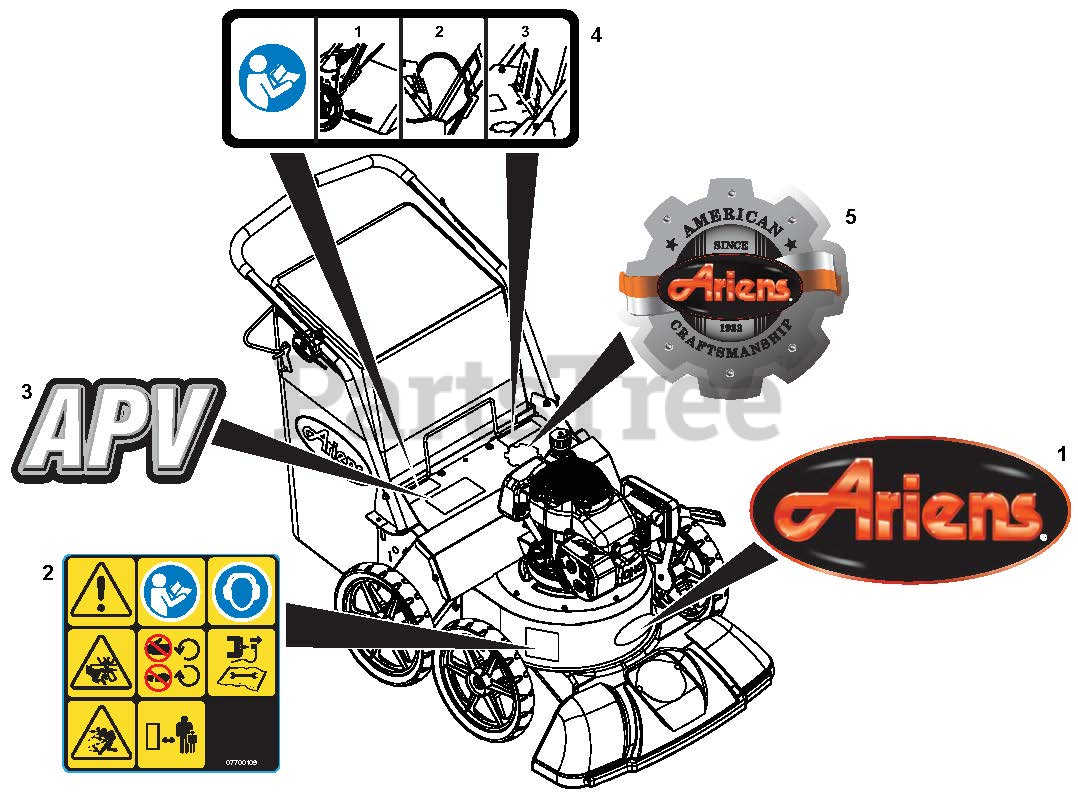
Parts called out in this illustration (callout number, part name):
1	DECAL, ARIENS JEWEL (LARGE)
2	DECAL,VAC WARNING ISO
3	DECAL - APV
4	DECAL, APV BAG INSTALLATION
5	DECAL, ARIENS HERITAGE-LARGE
